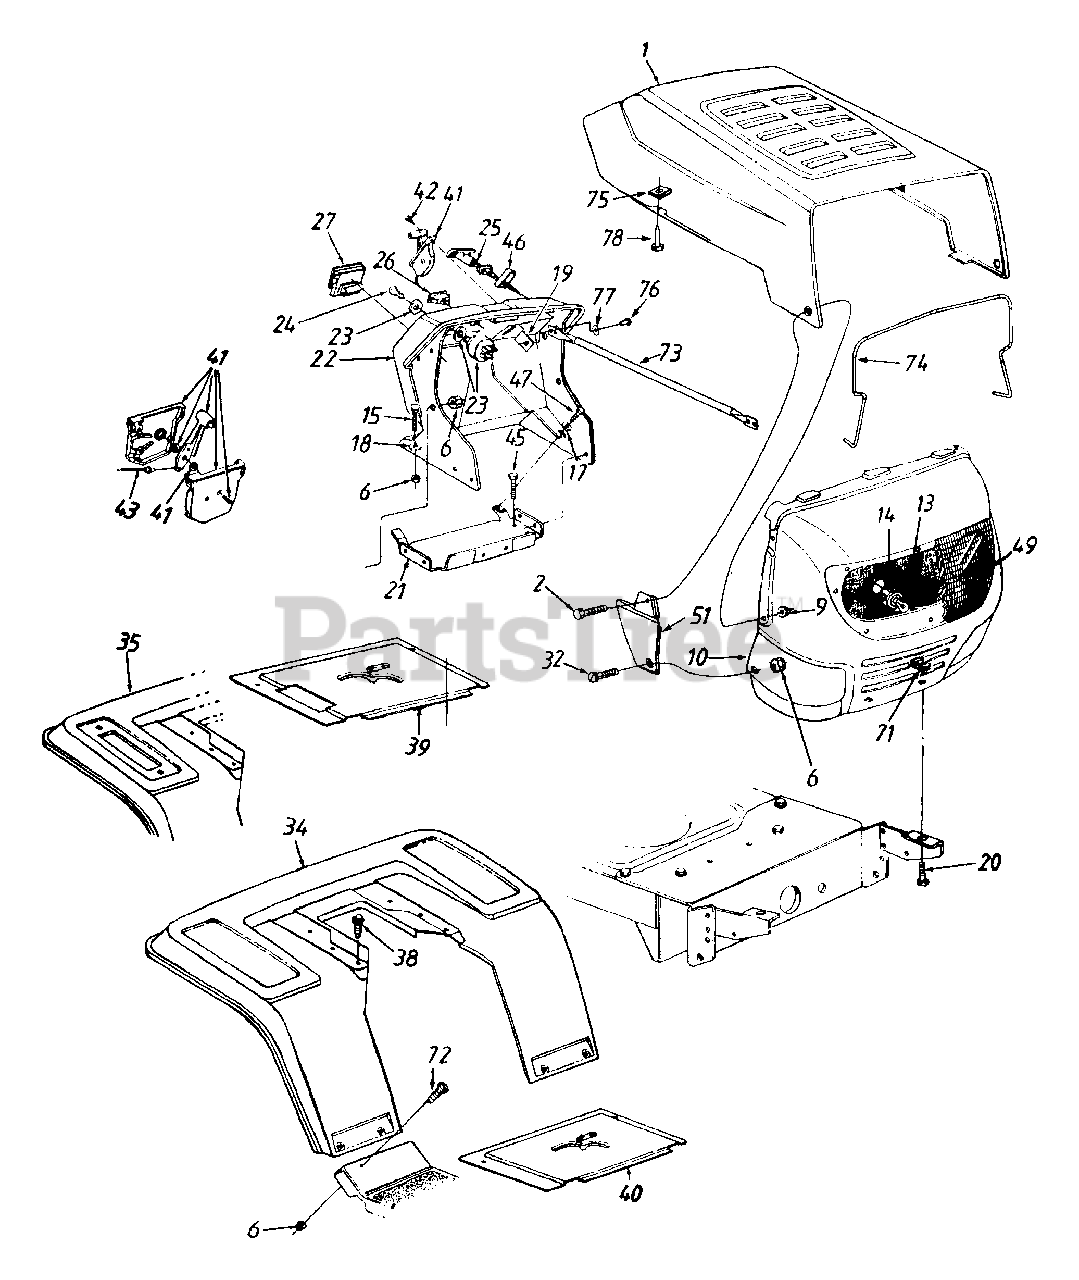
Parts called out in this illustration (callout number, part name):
6	Hex Sems Nut 1/4-20 Thd.
9	Flange L-Nut 1/4-20 Thd.
13	Lamp
14	Socket
15	Carriage Bolt 1/4-20 x .75" Lg.
17	Fl-Wash. .281" I.D. x .73" O.D.
18	Bolt Retainer 1/4" I.D.
19	Speed Nut 1/4-20 Thd.
20	Hex Bolt 5/16-18 x .1" Lg. (Gr.5)
23	Ignition Switch
24	Ignition Key
25	Choke Control 23" Lg.
26	Light Switch
27	Ammeter
32	Pan Hd. Scr. 1/4-20 x .75" Lg.
41	Throttle Box Ass'y.
42	Truss Mach. AB-Tap Scr. #10 x .5"
43	Throttle Control Wire 18.5" Lg.
45	Hex Wash. Hd. B-Tap Scr.
46	Choke Retainer
47	Hex TT-Tap Scr. 1/4-20 x .75" Lg.
49	Lens
72	Truss Mach. Scr. 1/4-20 x .5" Lg.
75	Speed Nut
76	Hex Bolt 1/4-20 x 5/8" Lg.
77	Fl-Wash. .283" I.D. x .75" O.D.
78	Hex Hd. Tap Scr. #10-16 x .75"
17870A-0483	FENDER-RR W/FRAME - CHARCOAL GRAY (0483)
17870A-0498	FENDER-RR W/FRAME - OLD CUB YELLOW (0498)
17870A-0638	FENDER-RR W/FRAME - MTD/TROY-BILT RED (0638)
17870A-0667	FENDER-RR W/FRAME - MIDNIGHT BLUE (0667)
